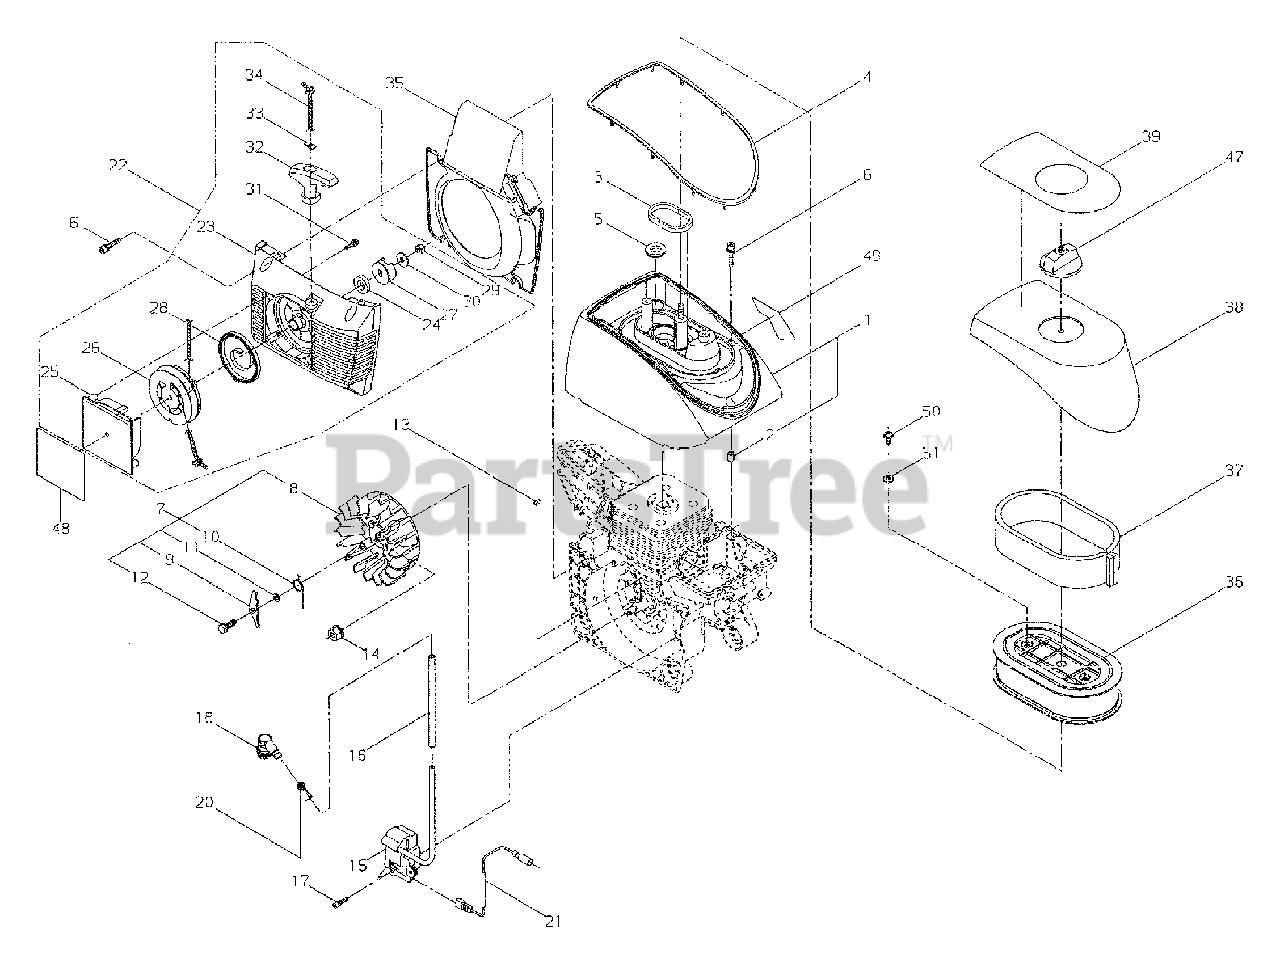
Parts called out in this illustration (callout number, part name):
1	ENGINE COVER KIT
3	SEAL
4	SEAT, SEAL
5	PLUG
6	BOLT
7	FLYWHEEL
8	FLYWHEEL
9	RATCHET
10	SPRING
11	COLLAR
12	BOLT
13	KEY - 3X10
14	NUT - 8
15	COIL
16	TUBE
17	SCREW - 4X16
18	CAP, SPARK PLUG
20	TERMINAL, SPARK PLUG CAP
22	STARTER ASSY
23	CASE, STARTER
24	SEAL, OIL
26	REEL, ROPE
27	DOG
28	SPRING, REWIND
29	NUT - 6
30	WASHER
32	GRIP, STARTER
33	RETAINER, ROPE
34	ROPE
35	DEFLECTOR, AIR
36	FILTER, AIR
37	PRE-FILTER
38	COVER, AIR FILTER
39	LABEL - CAUTION
47	KNOB
48	LABEL - TRADE
49	LABEL - INSTRUCTION
50	SCREW
51	WASHER - VINYL
